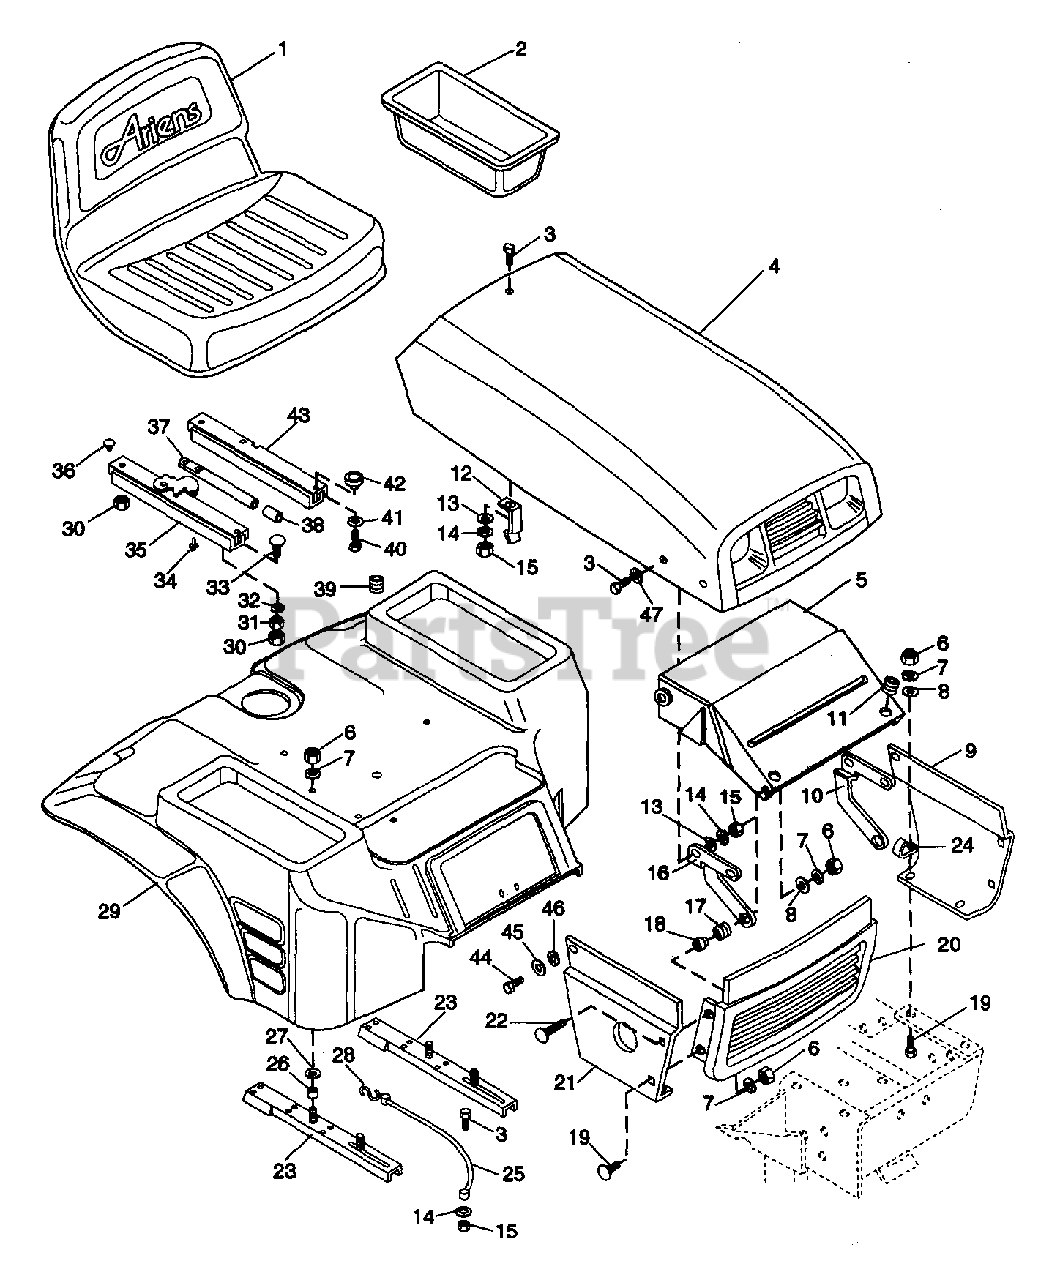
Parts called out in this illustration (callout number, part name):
1	SEAT
3	SCR .25-20X.75 TS PH PL
4	HOOD & GRILL
5	MUFFLER SHIELD
6	NUT-HEX .375-16
7	WSHR-LK .375X.094 MED PL
8	WSHR-FL-STL .438X1.0X.083 PL
9	SIDE SHEET L.H.
10	L.H. HOOD HINGE
11	GROMMET .438ID X .688 OD
12	HOOD STOP
13	WSHR-FL-STL.281X.62X.065 PL
14	WSHR-LK .250X.077 HVY PL
15	NUT-HEX .250-20 PL
16	R.H. HOOD HINGE
17	GROMMET .50IDX.812OD
18	SPACER -FLANGED .390X.500X.781
19	BLT-RDHDSQSHNK .38-16X1.00 PL
21	SIDE SHEET R. H.
22	BLT-RDHDSQNK .38-16X2.00 SHTYW
23	SEAT SUPPORT
24	J-CLAMP
26	SPACER .380X.503X.281
27	WSHR-FL-STL .390X.750X.125 PL
29	REAR DECK
30	NUT-LK .312-18 GR A PL
31	NUT-HEX .312-18
32	WSHR-LK .312X.097 PL HVY
33	SCR-CAP BTHD.31-18X.875 GR5 PK
34	RVT-POP.187X.562 DOME ST
35	SEAT SLIDE R H
36	SCR-CAP BTHD.31-18X.50 GR5 YZ
37	SEAT SLIDE HANDLE
39	GROMMET
40	SCR-MCH .31-18X1.00 CRRH PL
41	WSHR-LK-EXT .313X.030 PL
42	SEAT SLIDE SPACER
43	SEAT SLIDE L H
44	SCR-MCH .31-18X.75 TSKBHD PL
45	WSHR-FL-STL.344X.688X.065PL
46	WSHR-LK-INT .313X.030 PL
47	WSHR-FL-STL .250X.562X.049 PL
